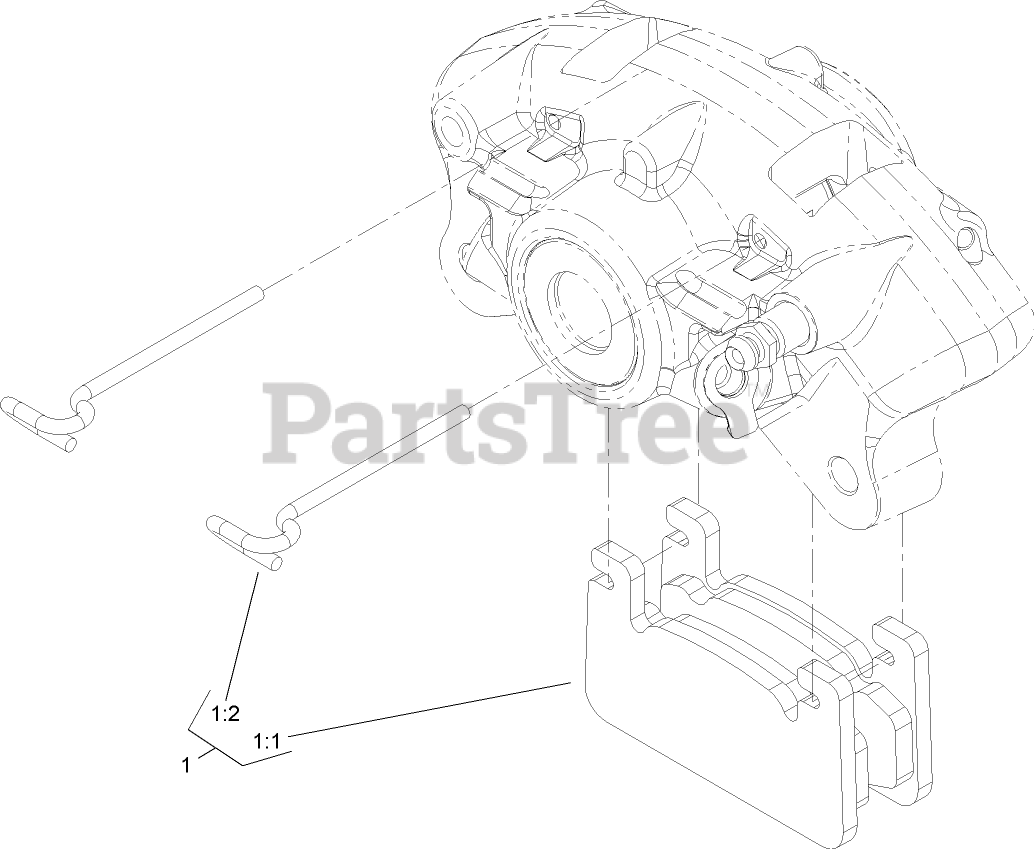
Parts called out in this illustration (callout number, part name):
1	FRICTION PAD AND PIN KIT
1:1	Loose Parts Package
1:2	Loose Parts Package
